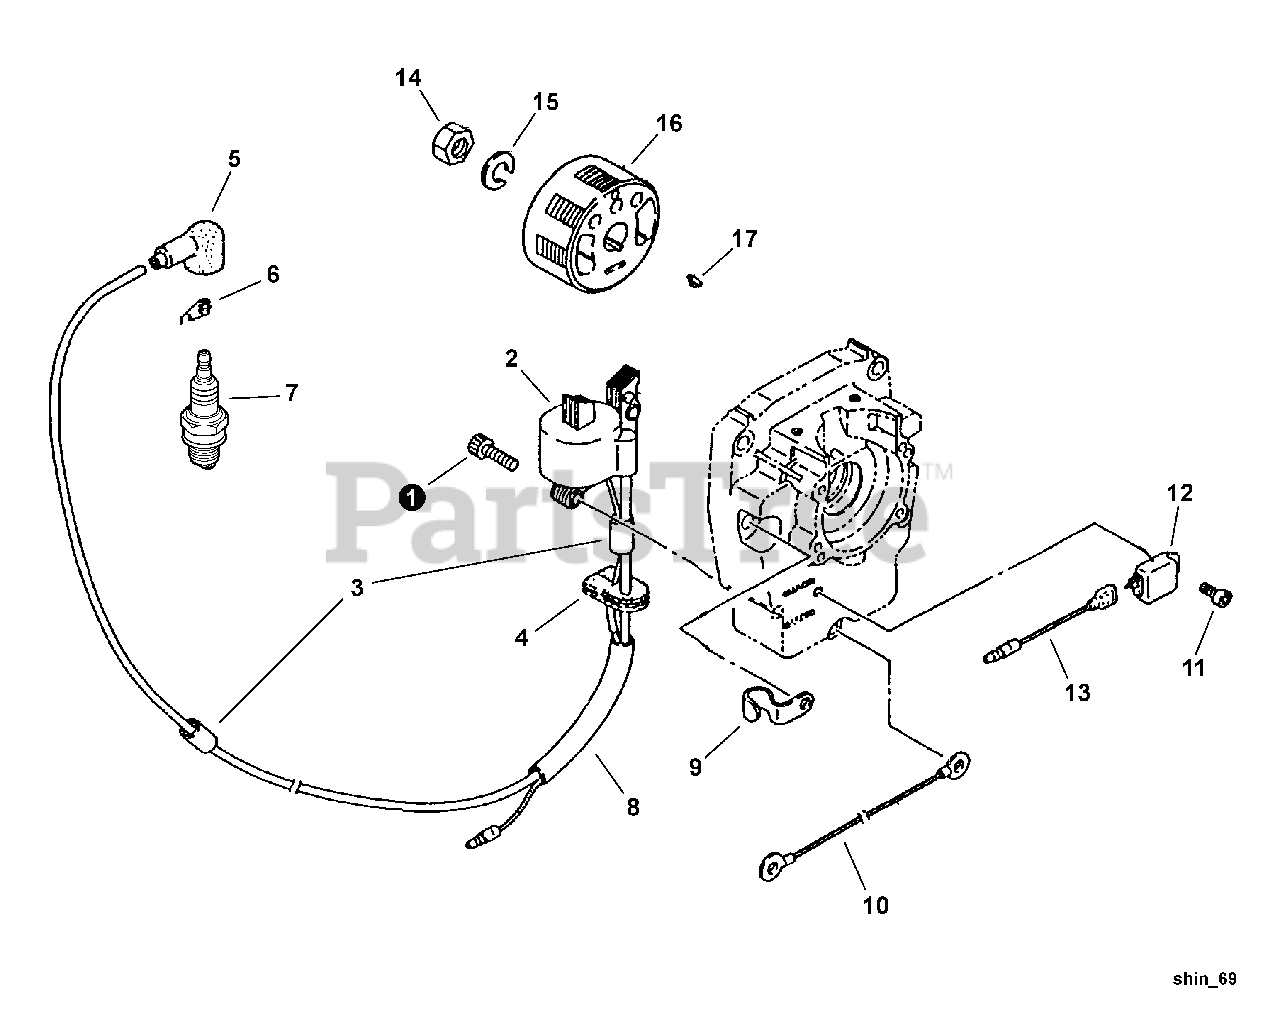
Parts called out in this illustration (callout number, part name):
1	SCREW - 5X20
2	COIL, IGNITION
3	SUPPORT, PIPE
4	GROMMET
5	CAP, SPARK PLUG
6	TERMINAL, SPARK PLUG CAP
7	SPARK PLUG -- C-CJ8
8	TUBE
9	CLIP
10	LEAD - GROUND
11	SCREW - 4X10
12	UNIT
13	LEAD - IGNITION
14	NUT - 10
15	LOCKWASHER - 10
16	FLYWHEEL
17	KEY - 3X10
